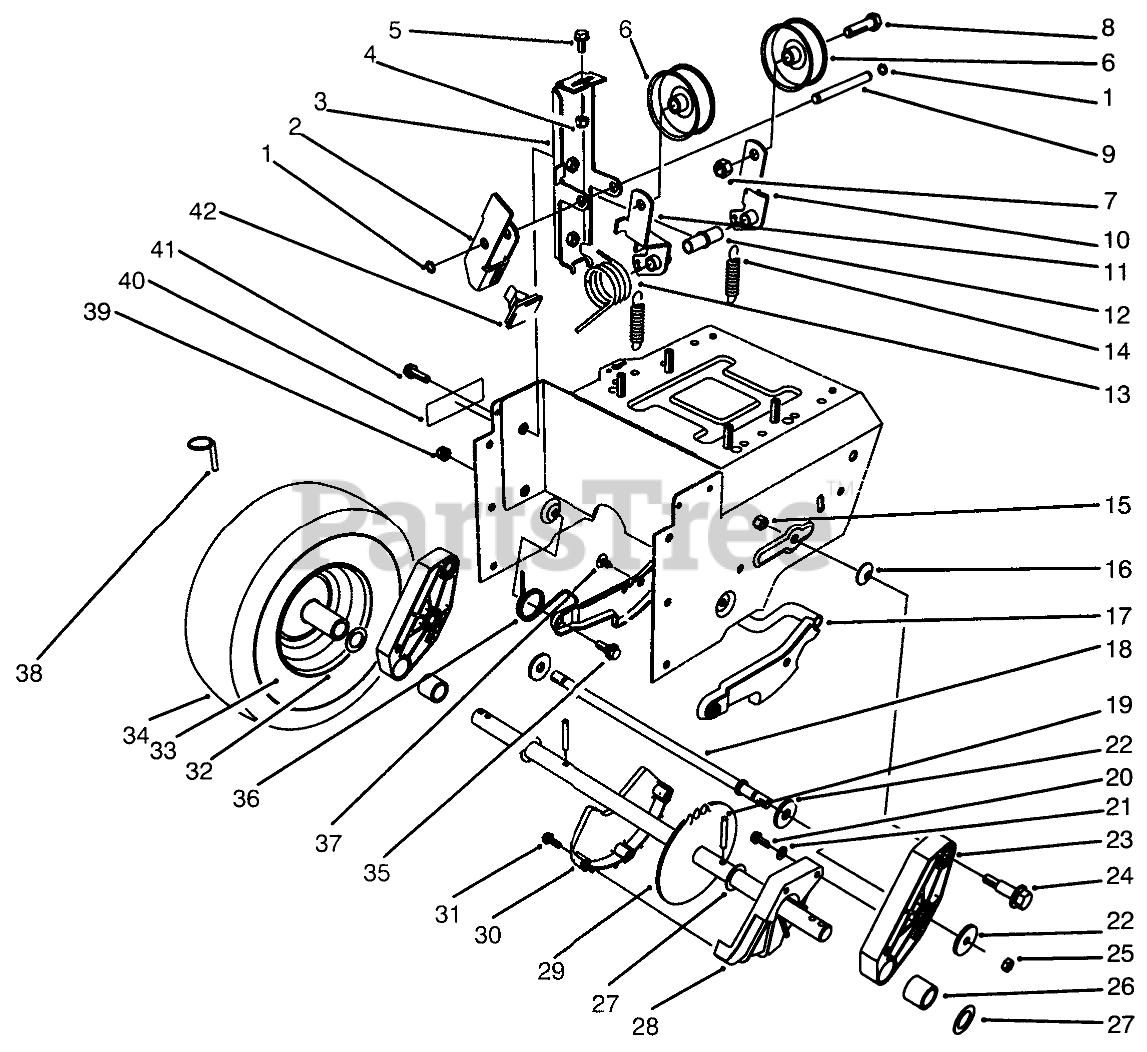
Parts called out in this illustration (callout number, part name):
1	Ring-Retaining
2	ARM-BRAKE
3	IDLER ARM BRACKET ASM
4	NUT-LOCK, NI
5	SCREW-HHF
6	PULLEY-IDLER
7	NUT-LOCK, NI
8	SCREW-HH
9	PIN-IDLER
10	TRACTION IDLER ARM ASM
11	IMPELLER IDLER ARM ASM
12	WASHER-FLAT
13	SPRING-TORSION
14	SPRING-EXTENSION
15	NUT-LOCK, NI
16	WASHER-SPRING
17	Latch-Arm
18	ROD-LATCH
19	PIN-ROLL, SLOTTED
20	SCREW-HWH
21	WASHER-FLAT
22	WASHER-SUPPORT
23	Pivot Arm Assembly (Incl. Ref. #26)
24	BOLT-SHOULDER
25	NUT-LOCK, NI
26	BUSHING-AXLE
27	WASHER-THRUST
28	GUARD-CHAIN, LH
29	AXLE ASM
30	GUARD-CHAIN, RH
31	Screw
32	WHEEL
33	TUBE-INNER
35	SCREW-SHOULDER
36	SPRING-LATCH, TORSION
37	FASTENER-PANEL
38	PIN-LYNCH
39	NUT-LOCK, NI
40	DECAL-WARNING
41	SCREW-HHF
42	PAD-BRAKE
